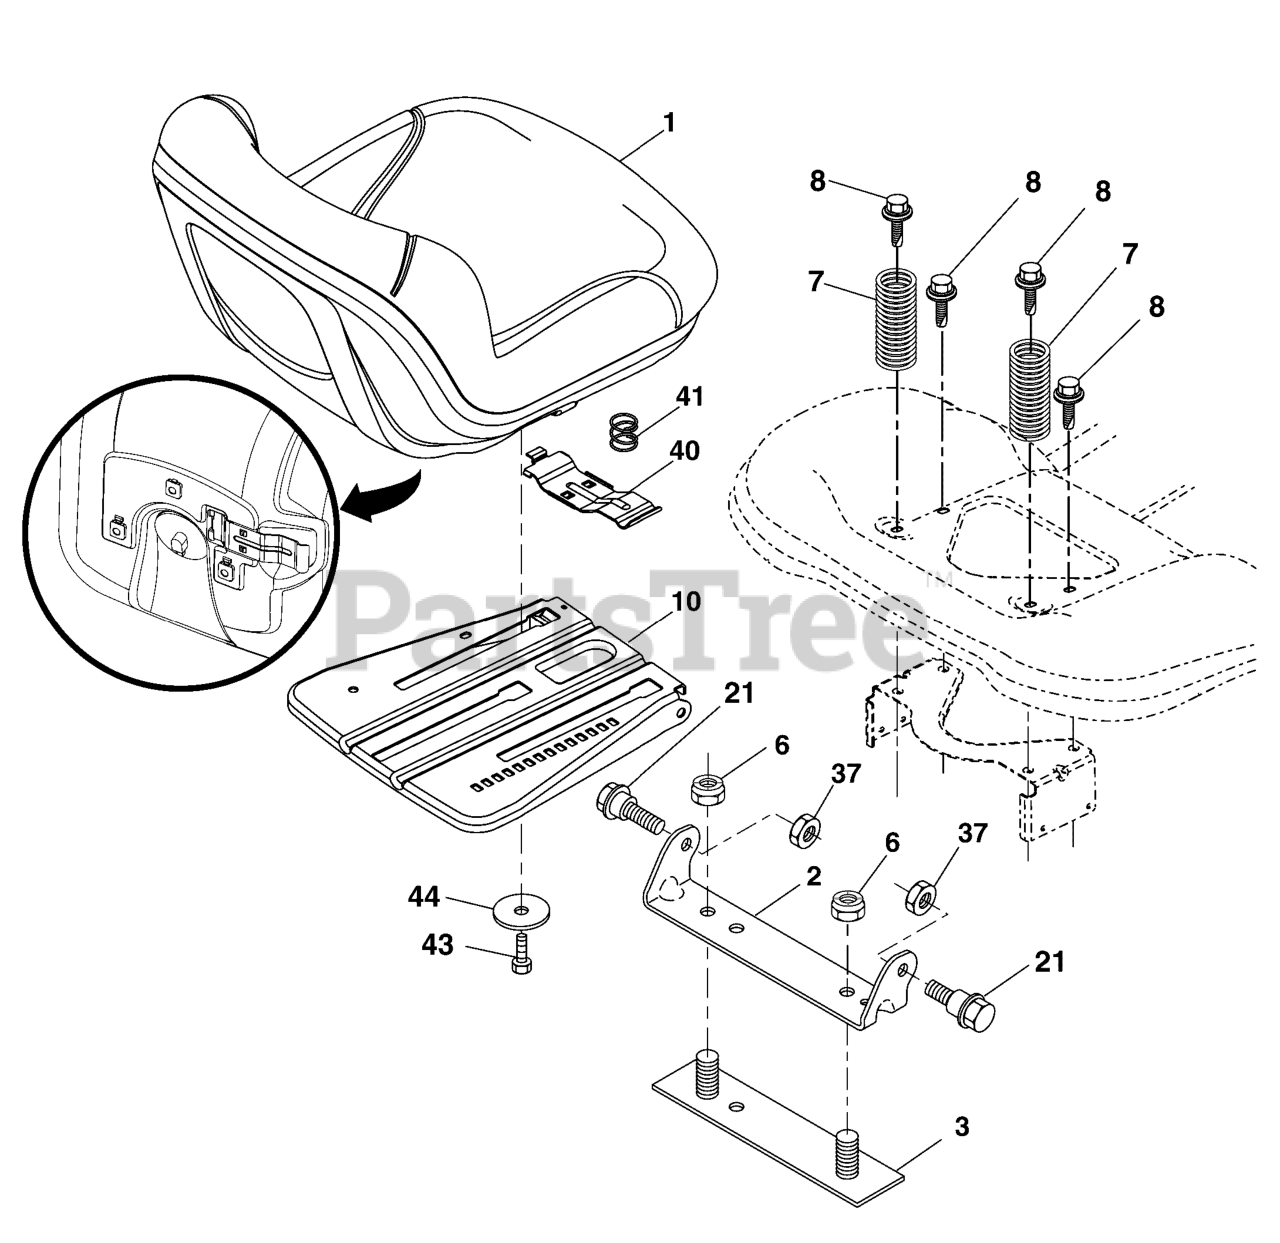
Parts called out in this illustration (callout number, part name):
1	SEAT
2	BRACKET, Pivot Fender
3	STRAP, Assembly Fender
6	NUT, Lock w/Insert, 3/8-16 UNC
7	SPRING, Seat
8	BOLT, SEMS, 5/16-18 UNC x 3/4
10	PAN, Seat
21	BOLT, Shoulder, 5/16-18
37	NUT, Lock, 5/16-18 UNC
40	HANDLE, Slide
41	SPRING, Latch
43	BOLT, 3/8-16 UNC x 3/4
44	WASHER, 13/32 x 2 3/8 x 12 Ga.
